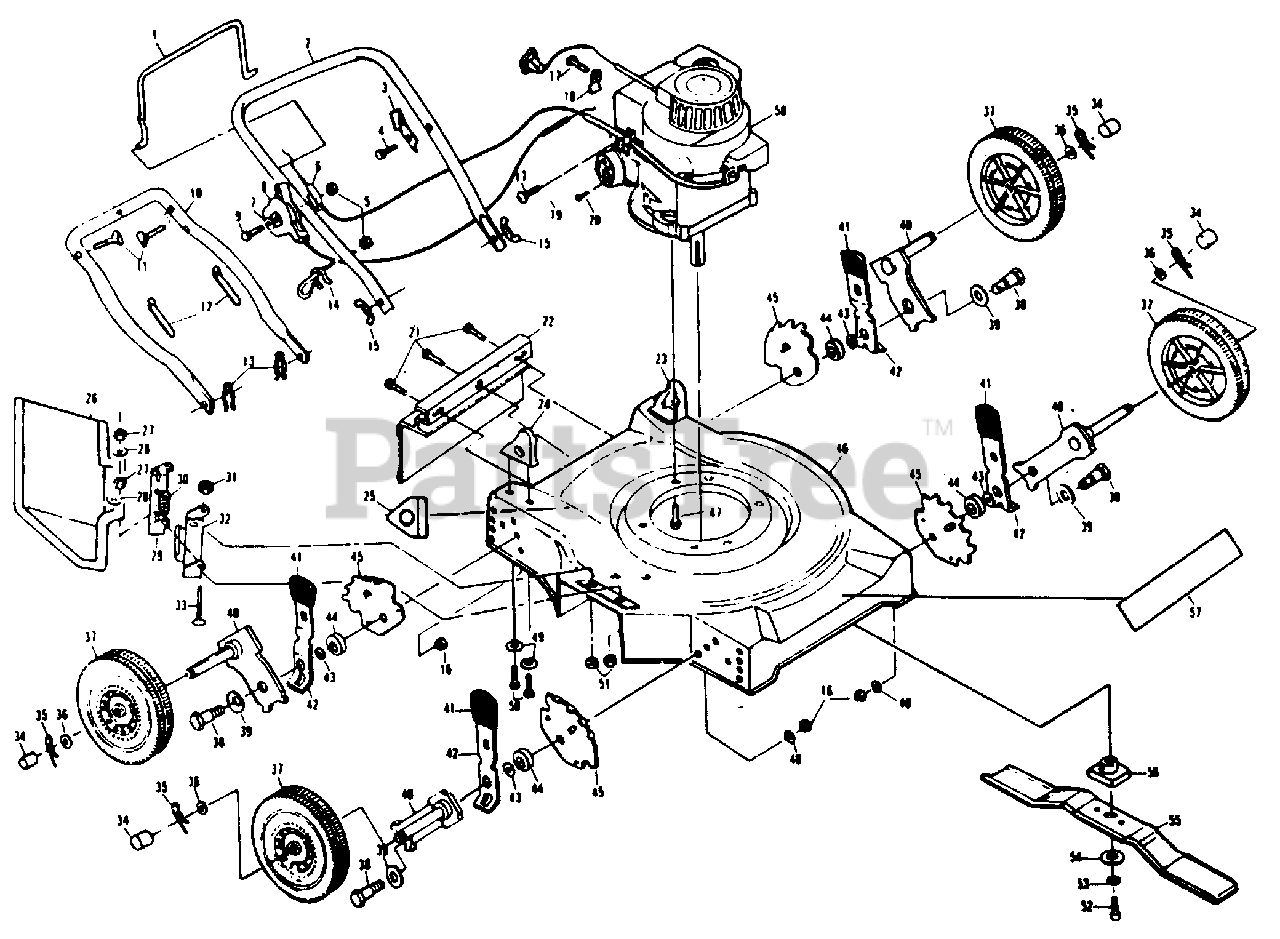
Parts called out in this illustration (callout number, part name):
1	Control Bar (AYP part number)
2	Upper Handle (AYP part number)
3	Up-Stop Bracket (AYP part number)
4	Hex Washer Head Screw (AYP part number)
5	Locknut (AYP part number)
6	Engine Zone Control Cable (AYP part number)
7	Flat Washer (AYP part number)
8	Throttle Control (AYP part number)
9	Machine Screw (AYP part number)
10	Lower Handle (AYP part number)
11	Handle Bolt
12	Wire Tie (AYP part number)
13	Hairpin Cotter (AYP part number)
14	Rope Guide (AYP part number)
15	Wing Nut (AYP part number)
16	Locknut (AYP part number)
17	Thread Rolling Screw (AYP part number)
18	Cable Clamp (Engine)
19	Screw (AYP part number)
20	Muffler Deflector
21	Hex Washer Head Tapping Screw (AYP part number)
22	Rear Skirt (AYP part number)
23	Handle Bracket Assembly (Left)
24	Handle Bracket Assembly (Right)
25	Danger Decal (AYP part number)
26	Discharge Guard (AYP part number)
27	Locknut (AYP part number)
28	Washer (AYP part number)
29	Discharge Bracket Assembly (AYP part number)
30	Torsion Spring (AYP part number)
31	Push On Speed Nut (AYP part number)
32	Housing Bracket Assembly (AYP part number)
33	Hinge Rod (AYP part number)
34	Hubcap (AYP part number)
35	Retainer Clip (AYP part number)
36	Flat Washer (AYP part number)
37	Wheel Assembly
38	Shoulder Bolt (AYP part number)
39	Belleville Washer (AYP part number)
40	Axle Arm Assembly (AYP part number)
41	Selector Knob (AYP part number)
42	Selector Spring
43	Flat Washer (AYP part number)
44	Spacer (AYP part number)
45	Wheel Bracket Adjuster (AYP part number)
46	Lawn Mower Housing (AYP part number)
47	Hex Head Thread Rolling Screw (AYP part number)
48	Washer (AYP part number)
49	Flat Washer (AYP part number)
50	Thread Cutting Screw (AYP part number)
51	Locknut (AYP part number)
52	Hex Head Screw
53	Helical Spring Washer (AYP part number)
54	Hardened Washer (AYP part number)
55	20" Blade.
56	Blade Adapter (AYP part number)
57	Decal "Poulan" (AYP part number)
